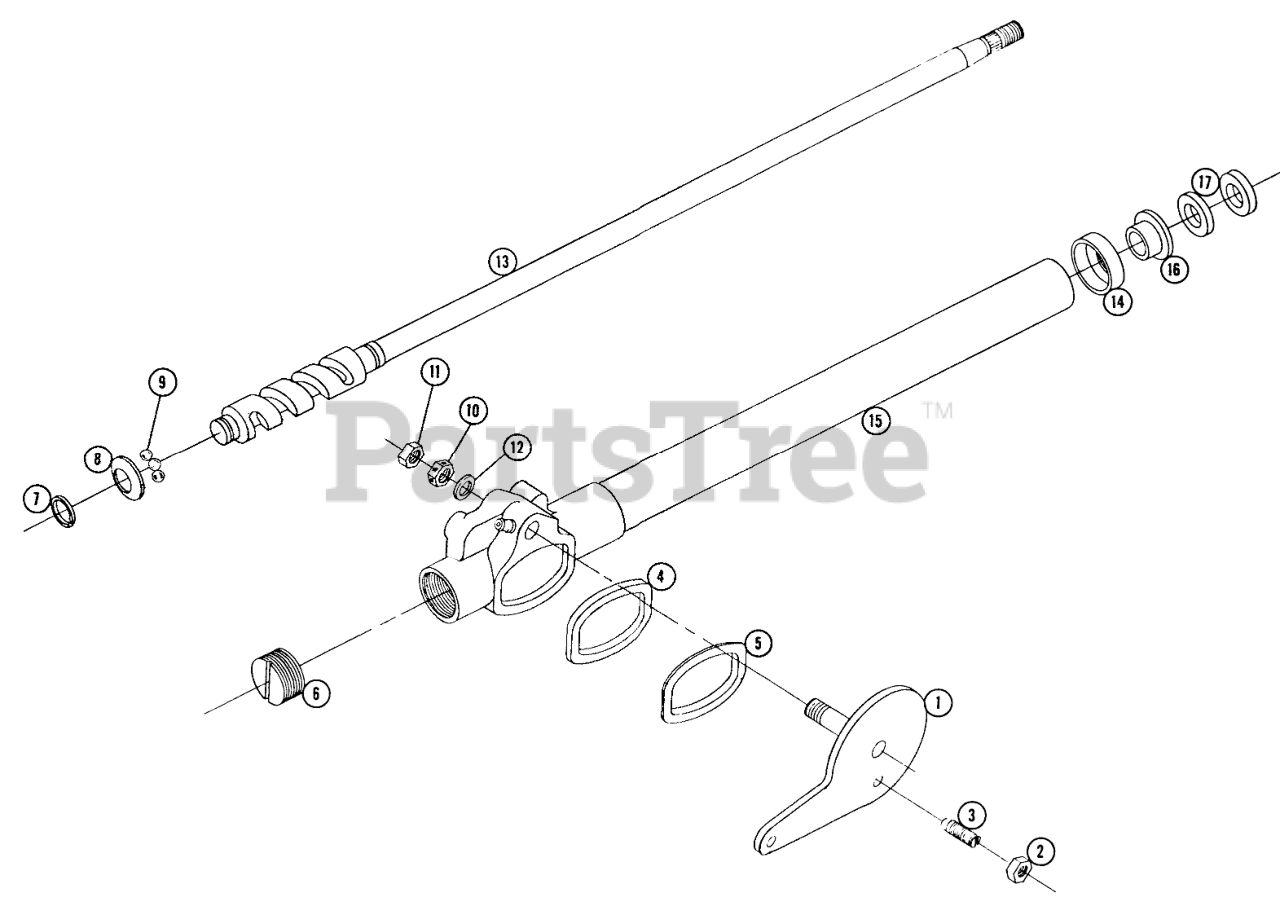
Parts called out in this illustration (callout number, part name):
1	Lever Arm (with cross bolt)
2	Nut-Hex Jam 1/2-20
3	Taper Stud
6	Adjusting Plug
7	Retaining Ring
8	Ball Cup
10	Nut Hex 5/8-11 Eslok
11	Hex Jam Nut 5/8-11
12	Plain Washer
13	Cam Tube Ass-y.
15	Housing Jacket Ass-y.
16	Bushing
17	Felt Washers
